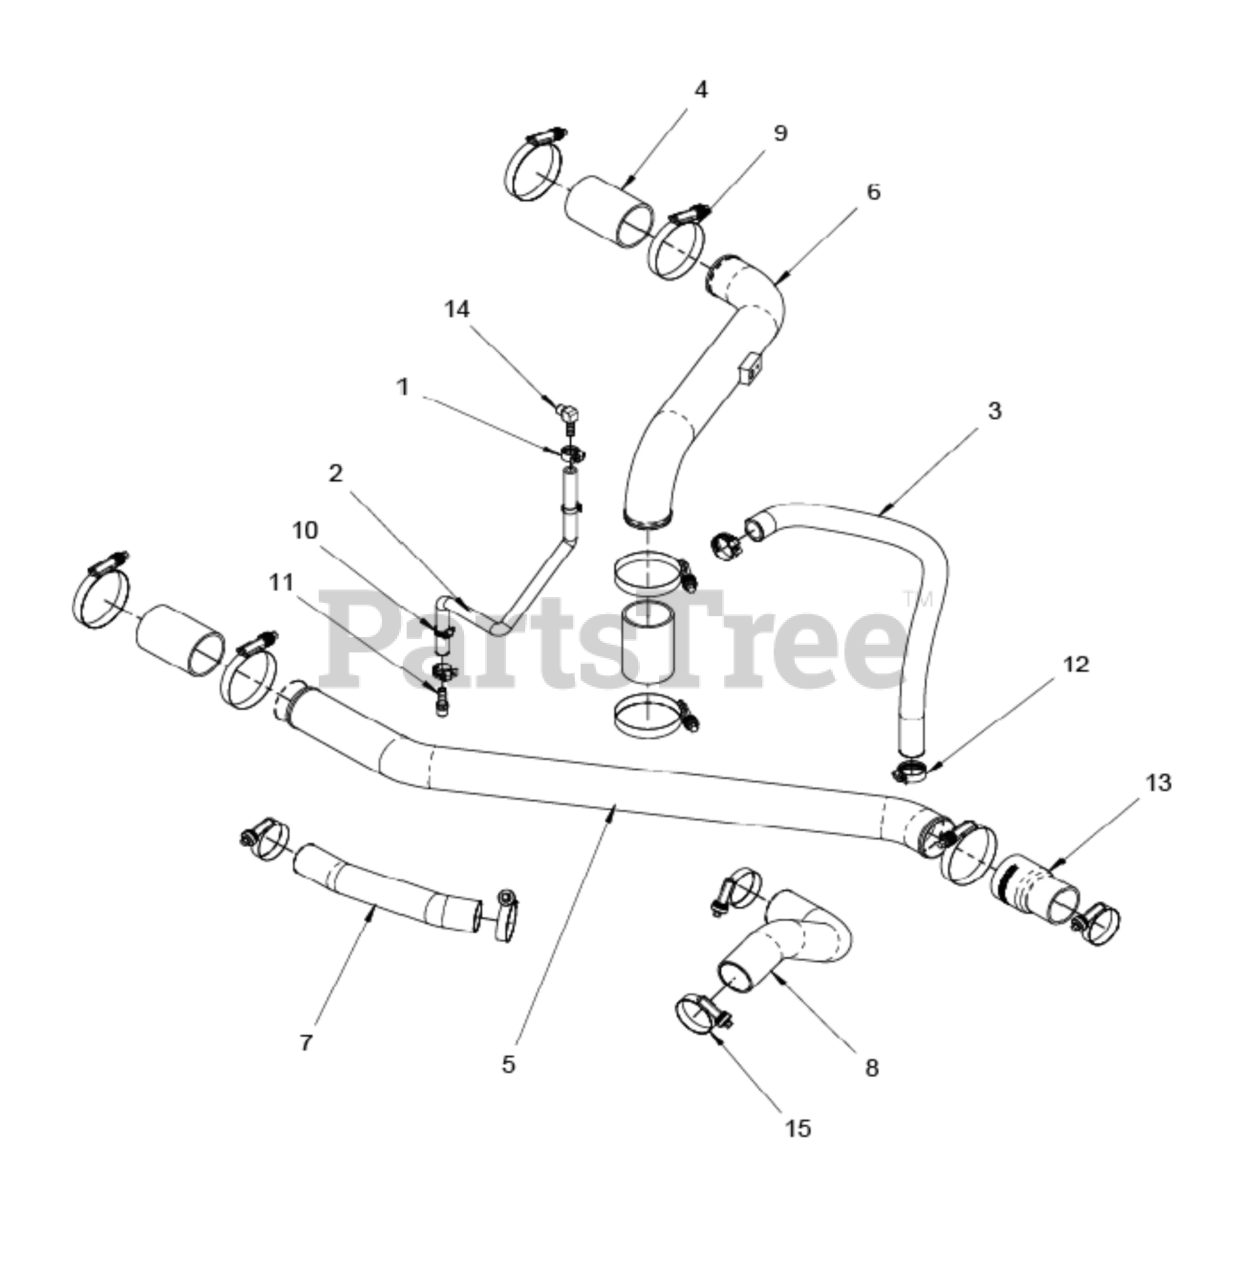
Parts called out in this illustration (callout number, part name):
2	*HOSE
4	*HOSE
5	*TUBE
6	*TUBE
10	*CLAMP
11	*FITTING
